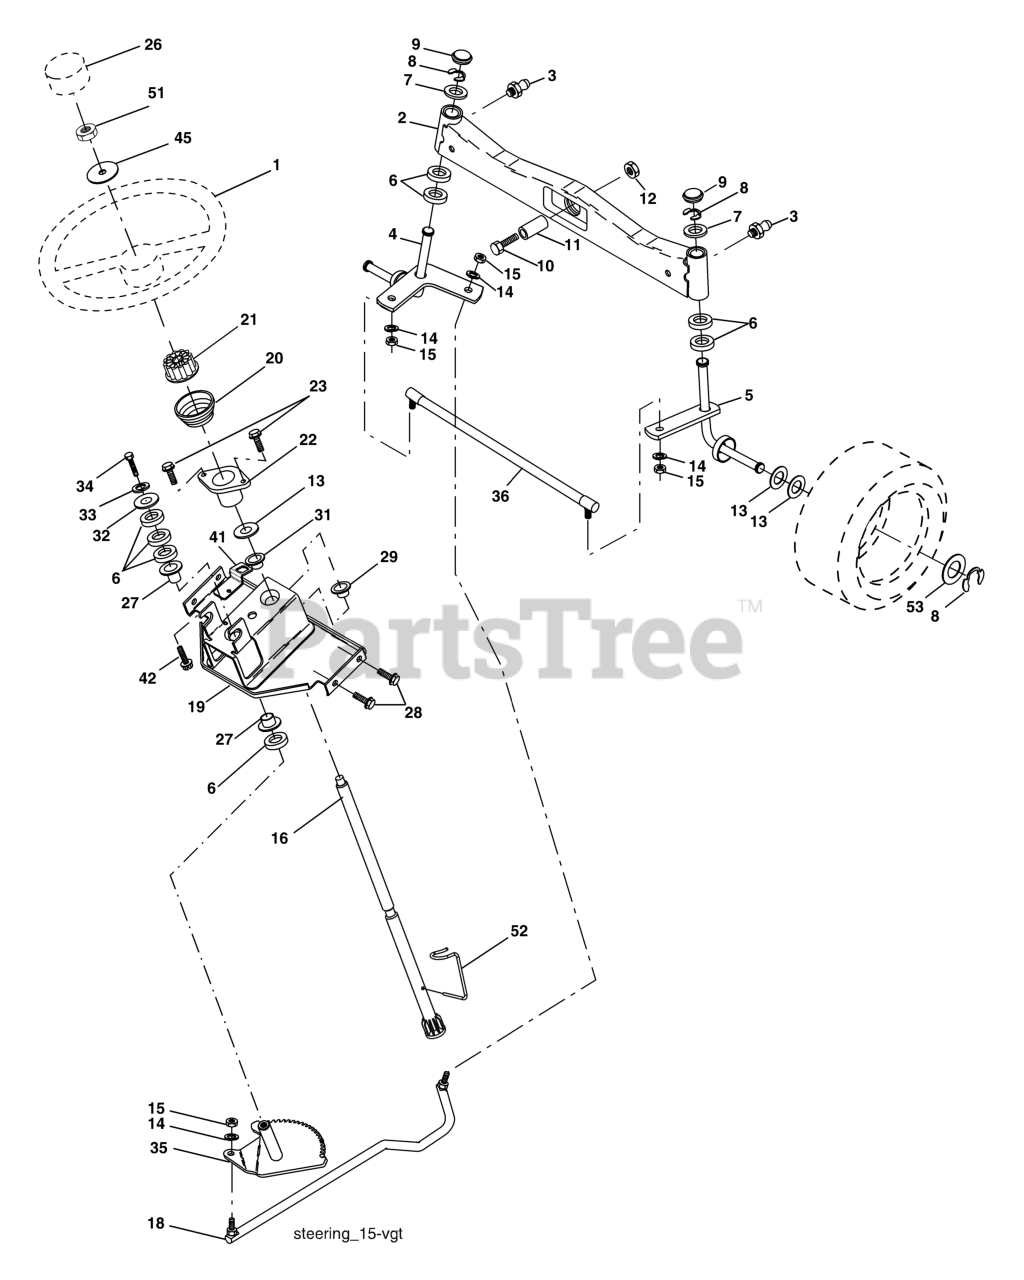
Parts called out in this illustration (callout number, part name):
1	WHEEL.STEERING.LEGEND2.GRY
2	AXLE.FRONT.CAST.MACHINE.W/ZERK
3	FITTING.GREASE.TAPERED
4	SPINDLE ASSY LH
5	SPINDLE ASM RH
6	THRUST WASHER
9	CAP.SPINDLE.BLACK
10	Bolt, Fin Hex 5/8-11 x 2-3/4
11	TUBE, PIVOT AXLE
12	NUT-LOC,FLANGE LT
14	WASHER, LOCK 3/8
15	NUT CROWNLOCK 3/8-24
16	SHAFT ASM, STEERING
18	DRAGLINK.VGT.54"
19	SUPPORT ASM., STEERING VGT
20	BOOT, STEERING
21	ADAPTER, WHEEL STNG..
22	BUSHING, STRG. BLK
23	SCREW.TT.#10-32X.5.3/8.FLANGE
26	INSERT.CAP.STRG.WH.GRAY
27	BRNG T
28	SCREW, 3/8-16X3/4
29	BEARING-FLANGE GT
31	BUSHING.NYLINER.
33	WASHER.LOCK.HVY.HLCL.SPR.5/16
34	BOLT.FIN.HEX.5/16-18X3/4
35	GEAR.ASM.SECTOR.PITMAN
36	ROD.TIE.NON-ADJUSTABLE
41	BRACKET INTERLOCK
42	Screw 5/16-18 x 1/2
44	EXTENSION STEERING PREMIUM
45	WASHER 9/16"ID, 2 3/8"OD
51	NUT.HEX.1/2-20
52	CLIP.STEERING
53	WASHER.HARDENED
